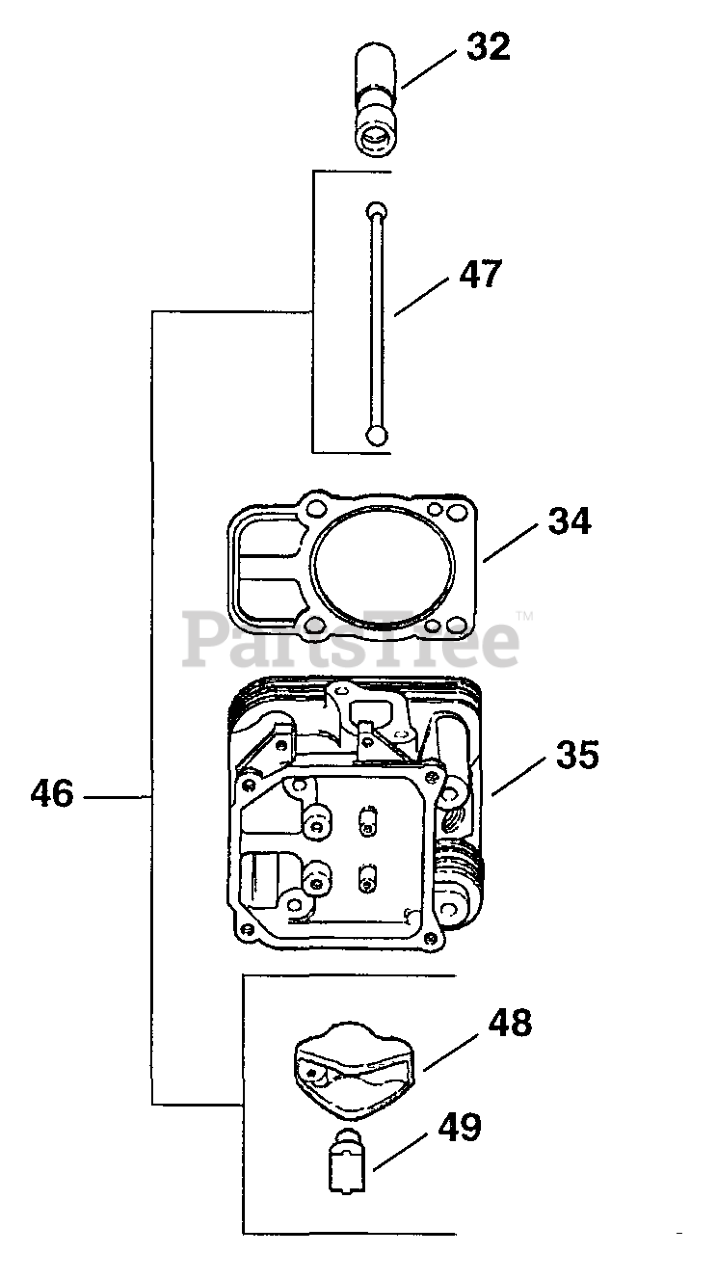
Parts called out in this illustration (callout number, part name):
32	LIFTER - USE 12 351 02
46	KIT, VALVE TRAIN
47	ROD, PUSH
48	ARM, ROCKER
49	PIVOT, CYLINDRICAL ROCKER ARM-USE 24 599 02-S
